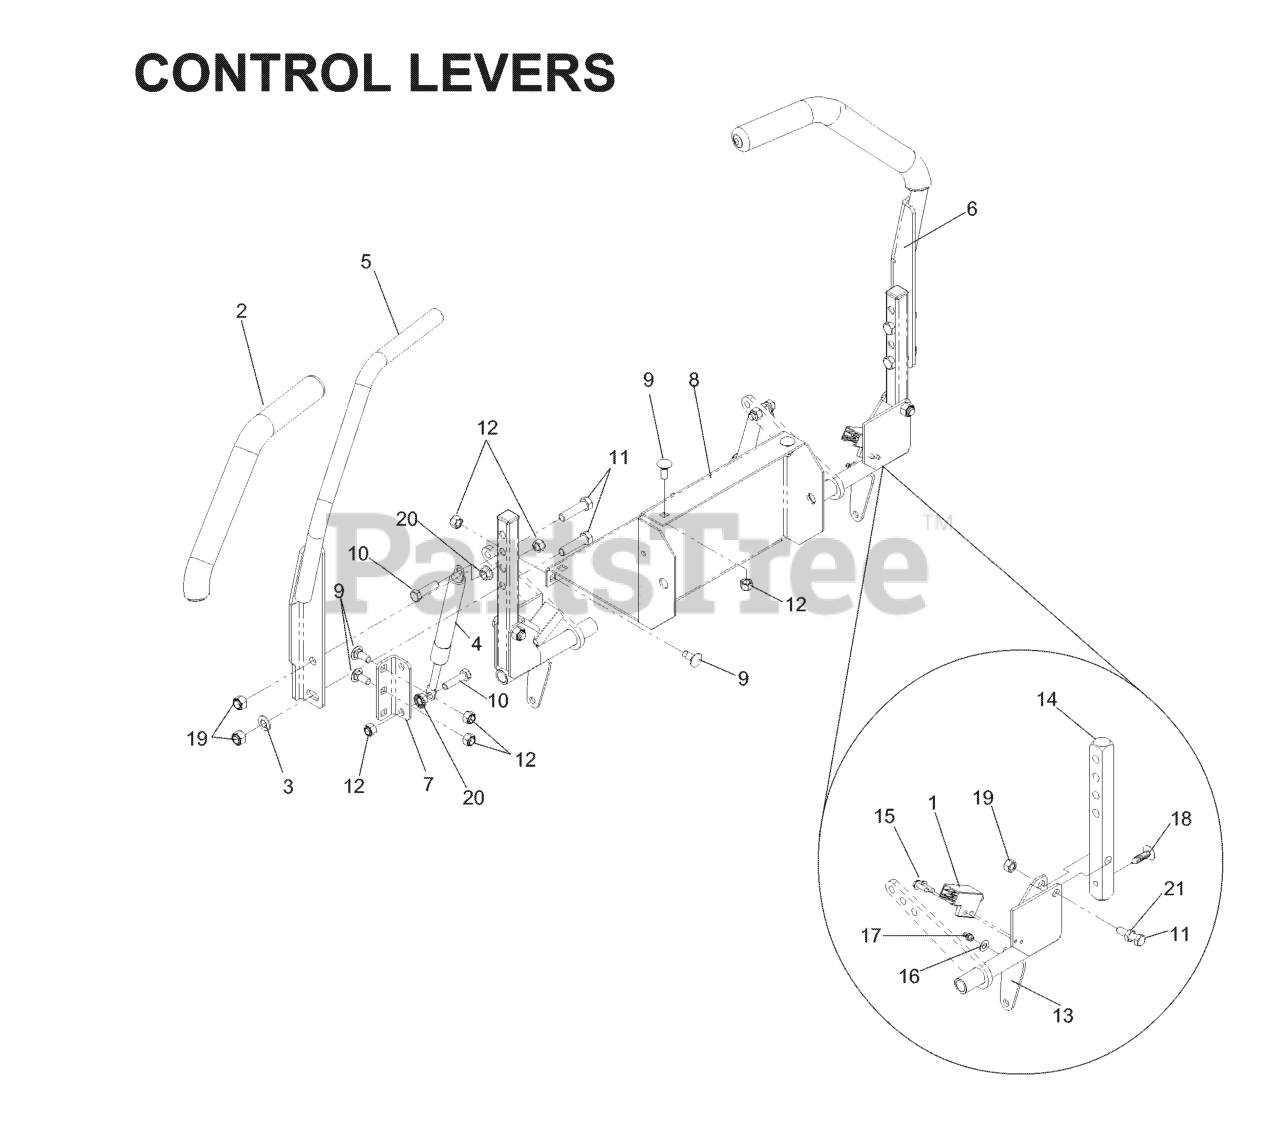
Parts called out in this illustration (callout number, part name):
1	SWITCH, INTERLOCK
3	WASHER, 3/8 DISC SPRING SPEC
5	RT DRIVE LEVER WLDMT
6	LT DRIVE LEVER WLDMT
7	DAMPENER BRACKET
8	BATTERY TRAY
9	BOLT 5/16C X 3/4" CARRIAGE
10	HCS 5/16C X 1 1/4
11	HCS 3/8-16 X 2-1/2 TPBLT
12	NUT 5/16 NYLOC
13	CONTROL WELDMENT, LEFT
14	CONTROL ARM
15	SCREW #10 X 1/2 SELF TAPPING
17	ZERK
18	RIVET, NYLON PUSH-IN
19	NUT 3/8-16 NYLOC
20	NUT 5/16C WHIZ
21	NUT 3/8C CENTERBLOCK
